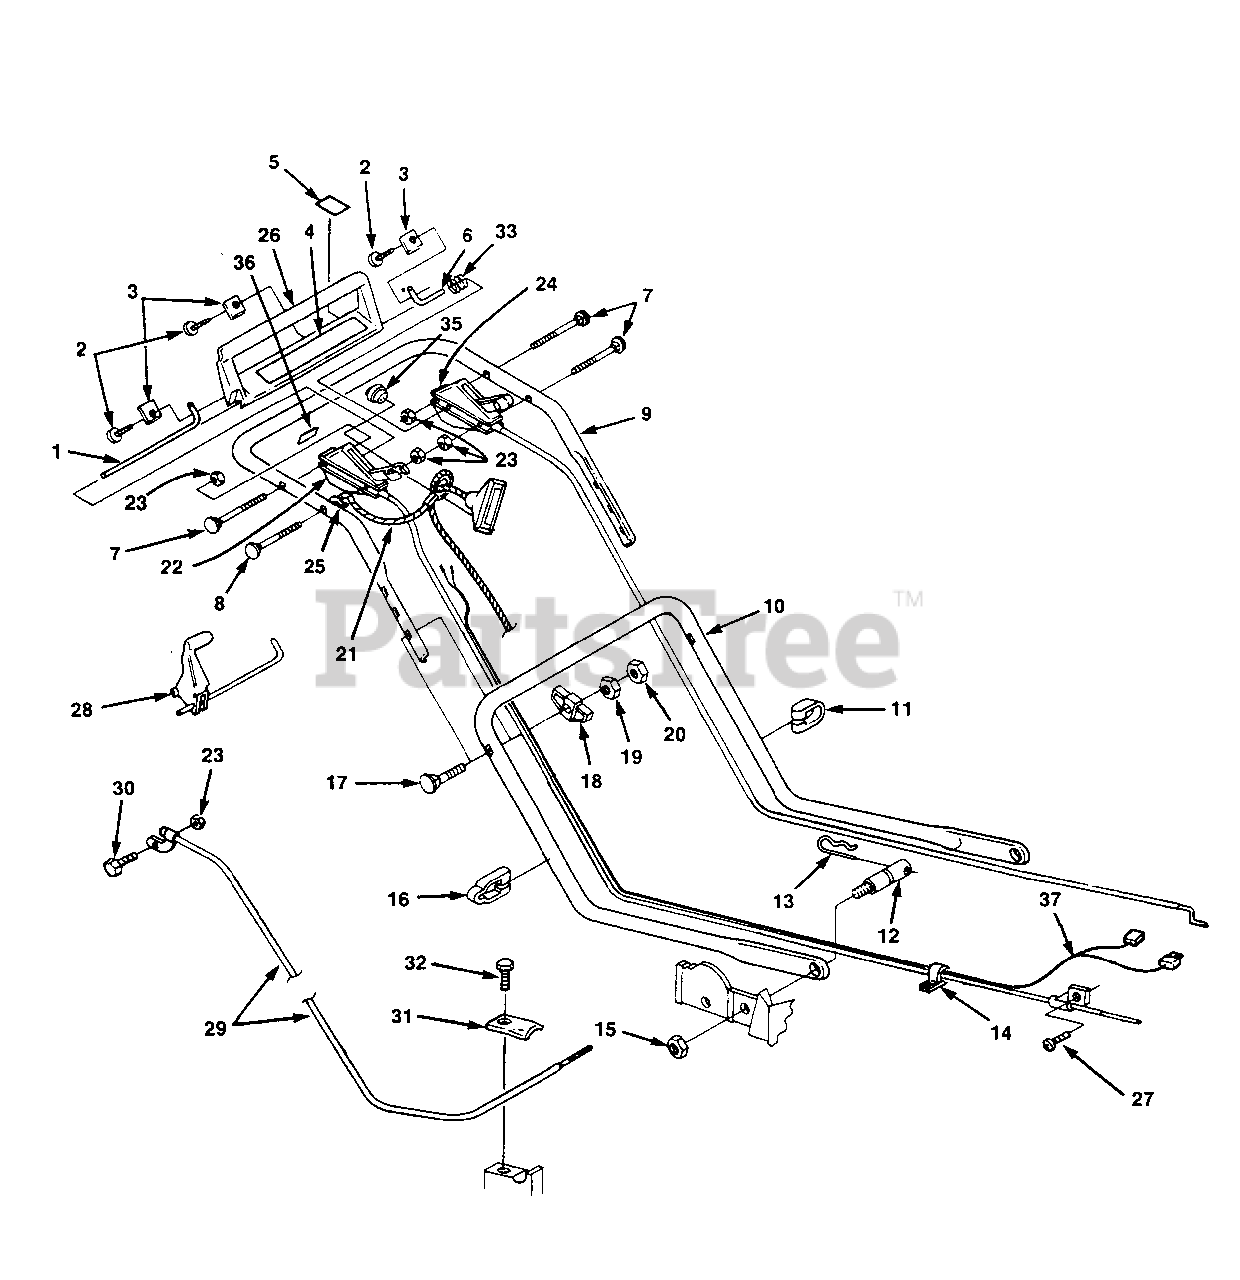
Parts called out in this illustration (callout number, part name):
1	SHAFT- Pivot
2	SCREW- Rd. Hd. 1/4-10 x 5/8
3	CLAMP- Pivot shaft
4	DECAL- Brake bail
5	DECAL- Blade rotation
6	SHAFT- Pivot (short)
7	BOLT- Sq. neck
8	BOLT- Sq. neck
9	HANDLE- Upper
10	HANDLE- Lower
11	CLAMP- Cable (single)
12	STUD- Handle mtg.
13	PIN- Cotter hair
15	NUT- Hex. flange 5/16-18
16	CLAMP- Cable (double)
17	BOLT- Sq. neck
18	KNOB- Handle
19	NUT- Hex. lock 5/16 x 18
20	NUT- Hex. lock 5/16 x 18
21	ROPE- Restraint
22	CONTROL- Manual start
23	NUT- Hex locking 1/4-20
24	CONTROL- Throttle
25	WASHER- Curved
26	BAIL- Brake control
27	SCREW- Hex hd. 10-32 x 3/8
28	LEVER- Traction
29	CABLE- Traction
30	SCREW- Hex hd. 1/4-20 x 1 1/2
32	SCREW- Hex. hd. 1/4-20 x 5/8
33	SPRING- Compression
